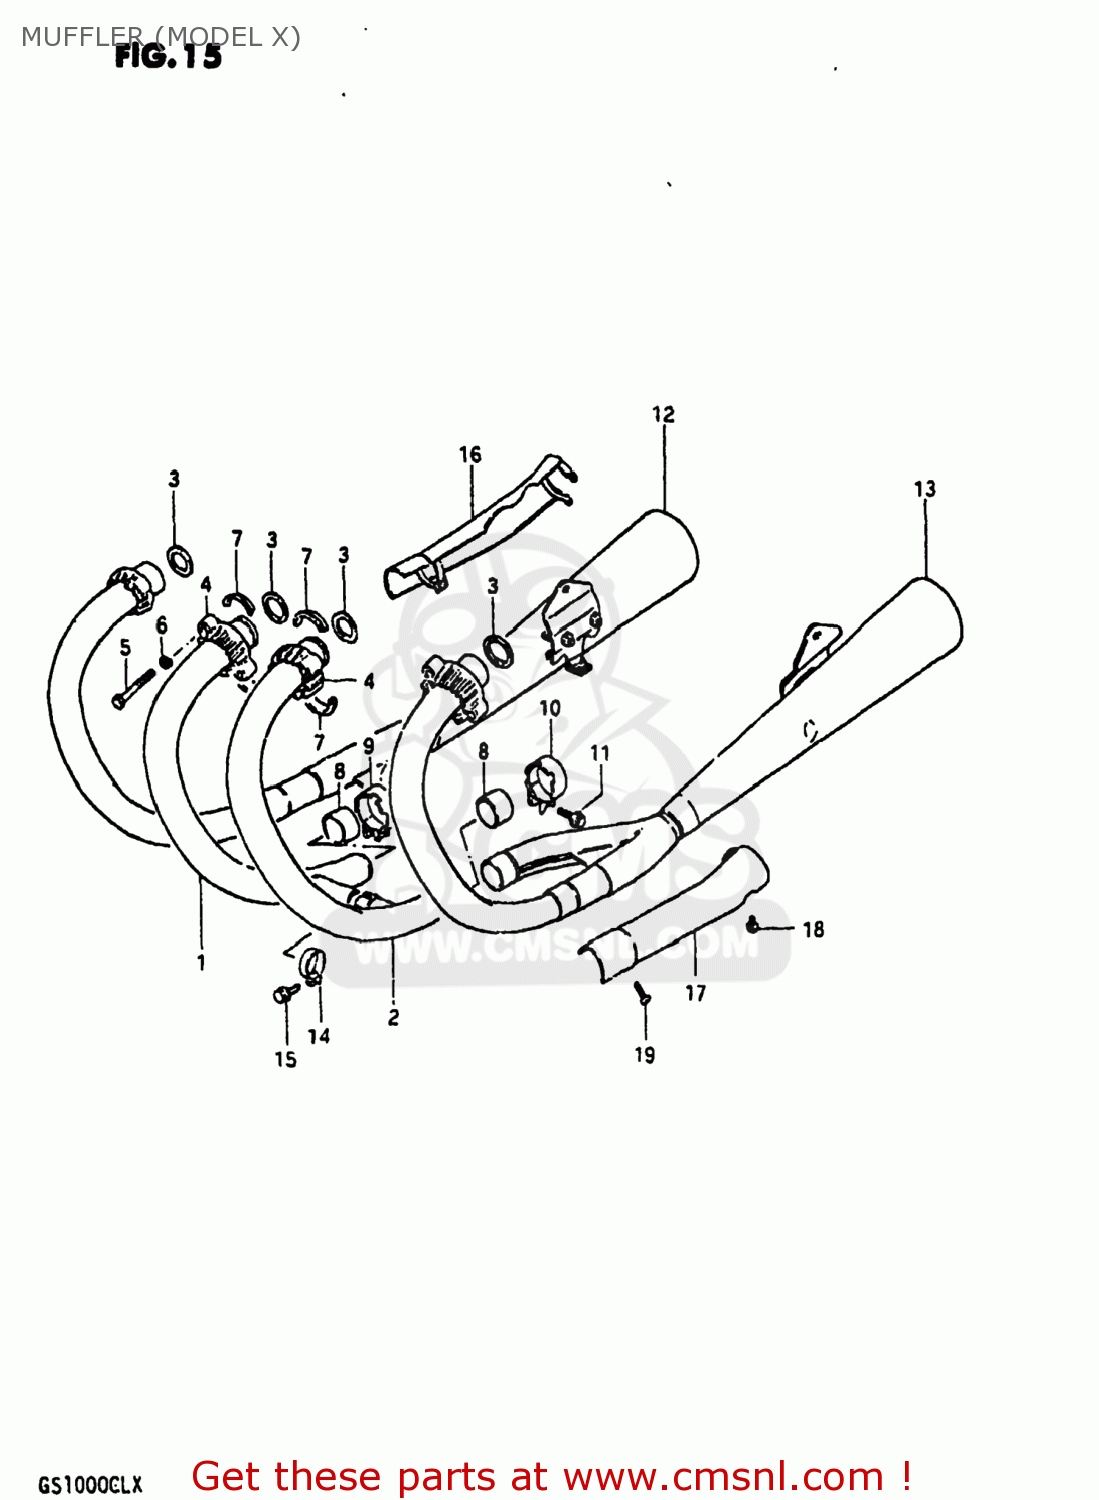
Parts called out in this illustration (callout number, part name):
1	PIPE,CENTER EXHAUST
2	COVER,EXHAUST PIPE
3	GASKET,EXHAUST PIPE (NAS)
4	CLAMP,EXHAUST PIPE
5	BOLT 8X45
6	LOCK WASHER
7	PLATE,EXHAUST
8	CONNECTOR,MUFFLER
9	CLAMP,MUFFLER CONNECTOR,R
10	CLAMP,MUFFLER CONNECTOR,L
11	BOLT
12	MUFFLER ASSEMBLY
13	MUFFLER ASSEMBLY
14	CLAMP
15	BOLT
16	COVER,MUFFLER,R
17	COVER,MUFFLER
18	SCREW
19	SCREW
